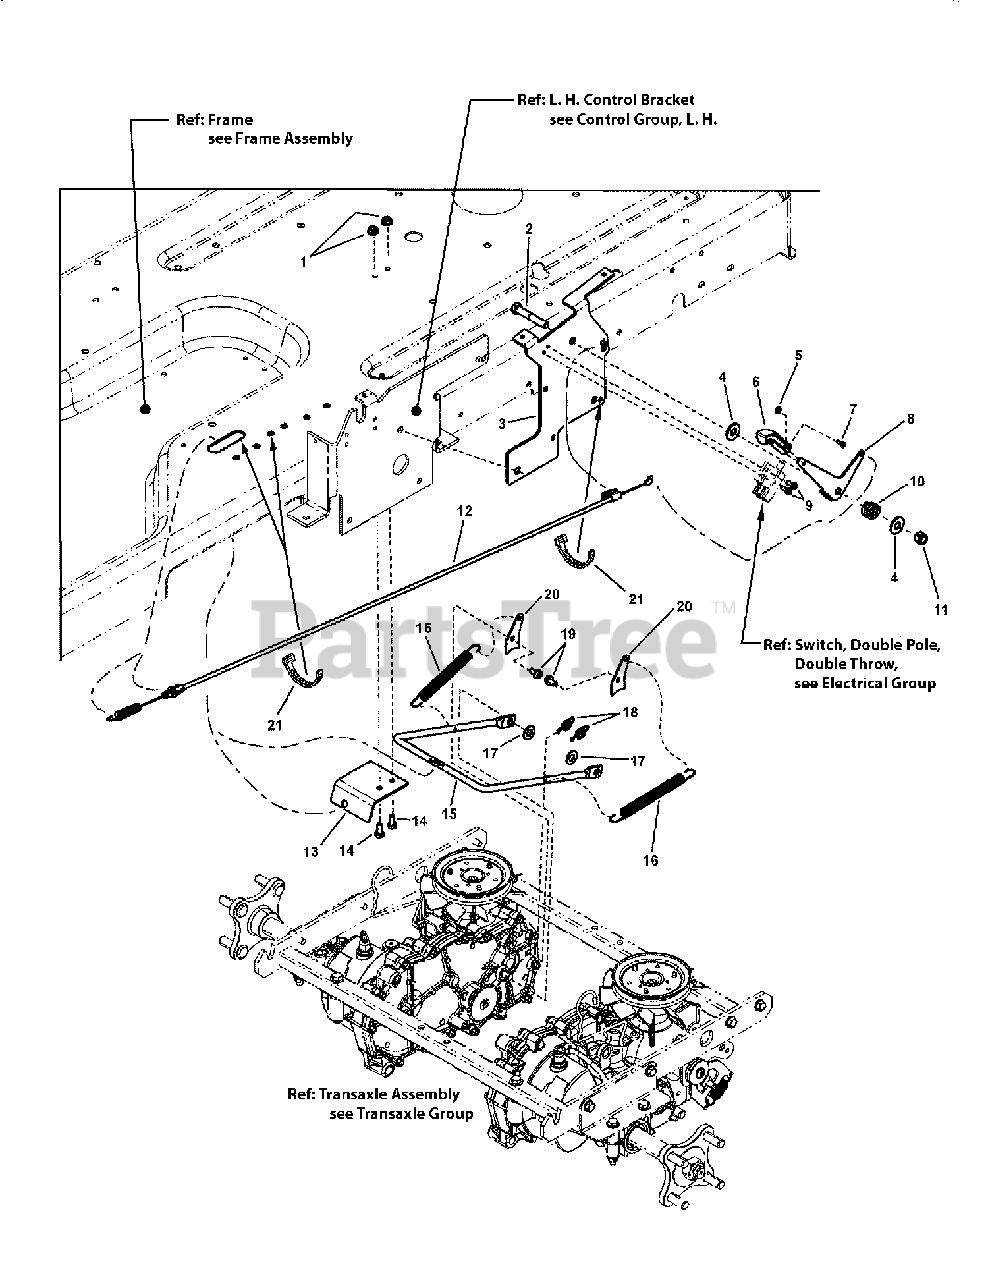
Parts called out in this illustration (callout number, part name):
1	NUT, 1/4-20 Hex Flange Lock, Black
2	SCREW, 3/8-16 x 2-1/4" Hex Head Cap, GR 5, YZ
3	BRACKET, Lever, Park Brake
4	WASHER, 3/8" Flat
5	NUT, #8-32 Hex, GR 2B
6	LEVER, Throttle Control
7	SCREW, #8-32 x 3/8" Cross Recess Filister Head, GR 2
8	LEVER, Brake, Park
9	SCREW, #10-24 x 1/2" Hex Washer Self-Tap, Torx
10	SPRING, Friction Pack
11	NUT, 3/8-16 Hex Nyloc, YZ
12	CABLE, Park Brake, RZT
13	BRACKET, Cable, Park Brake
14	SCREW, 1/4-20 x 5/8" Hex Head Cap, GR 5
15	ROD, Park Brake, RZT
16	SPRING, Extension, .562 OD x 4.250 Long x .049 Wire
17	WASHER, 3/8" Flat (SAE)
18	COTTER PIN, 1/2" Self Locking, YZ
19	SCREW, 1/4-20 x 1/2" Hex Washer Self-Tap
20	TAB, Spring, Park Brake
21	CABLE TIE, 7"
